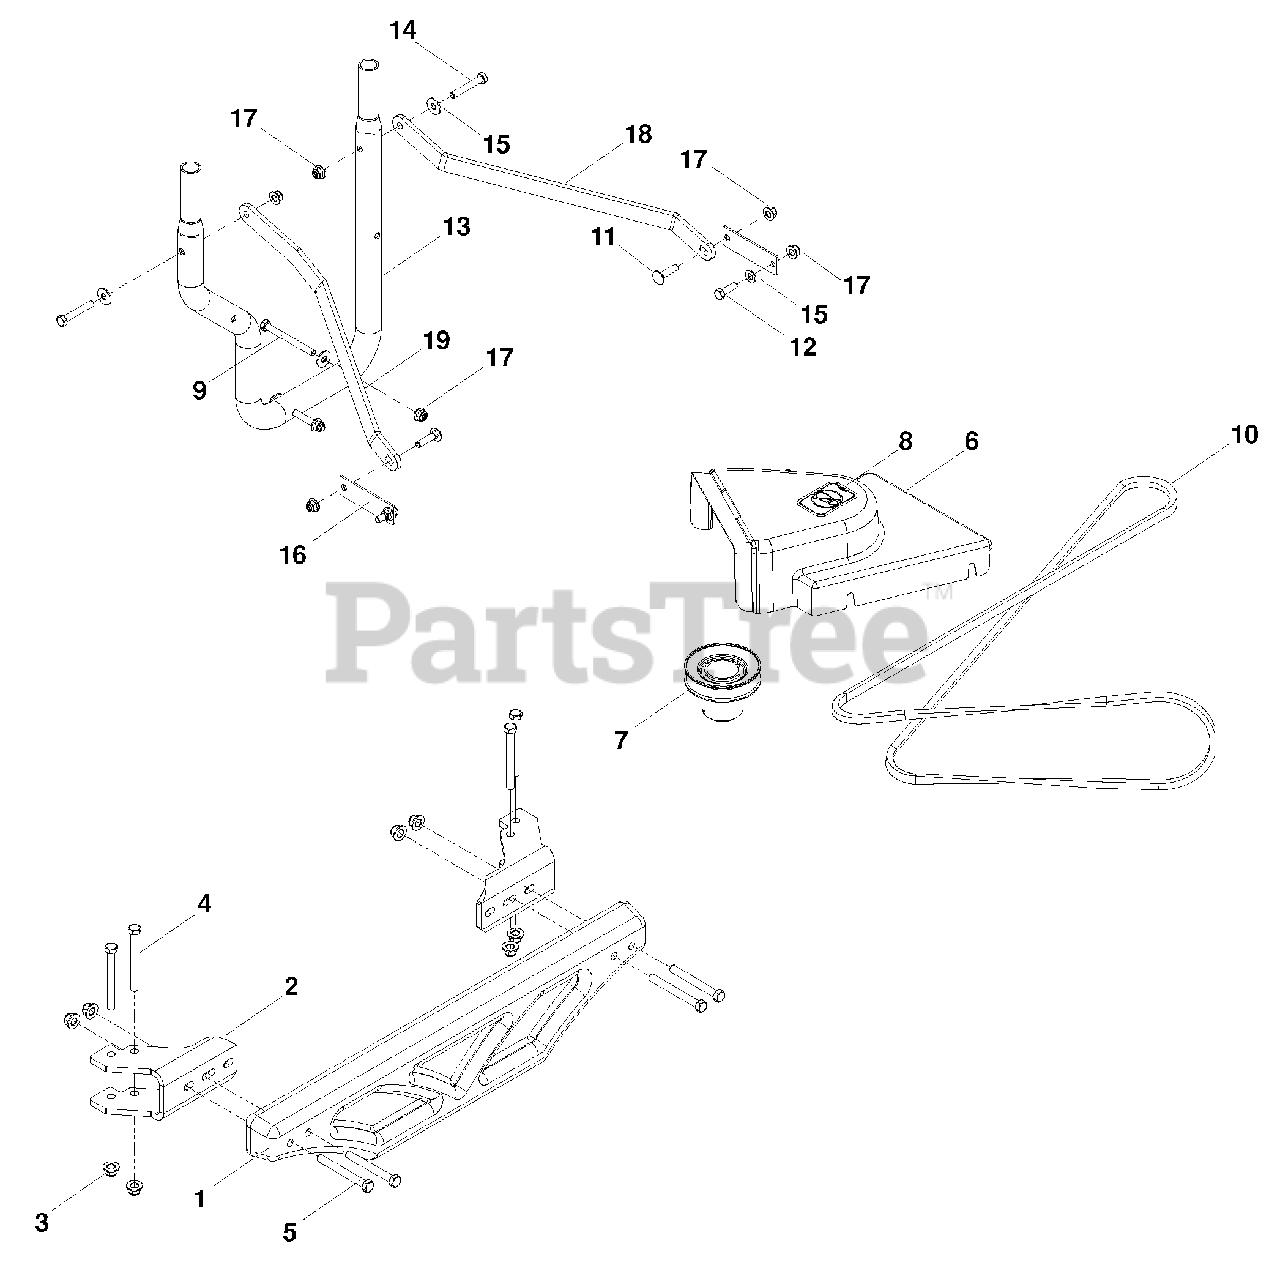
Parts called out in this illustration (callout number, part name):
1	Weight Plate
2	Weight Bracket
3	Nut 3/8-16 Hex Flange
4	Hcs 3/8-16 X 31/2
5	Hcs 3/8-16 X 3
6	Shield, Belt
8	Decal, No Step
9	Hcs 5/16-18 X 31/4
11	Rhsnb 5/16-18 X 11/4
12	Hcs 5/16-18 X 1
13	Tube, Mount
14	Hcs 5/16-18 X 2
15	Washer 5/16 Std Flt
16	Plate, Reinforcement
17	Nut 5/16-18 Hex Flg Nyloc
18	Strap, Support, Lt
19	Strap, Support, Rt
